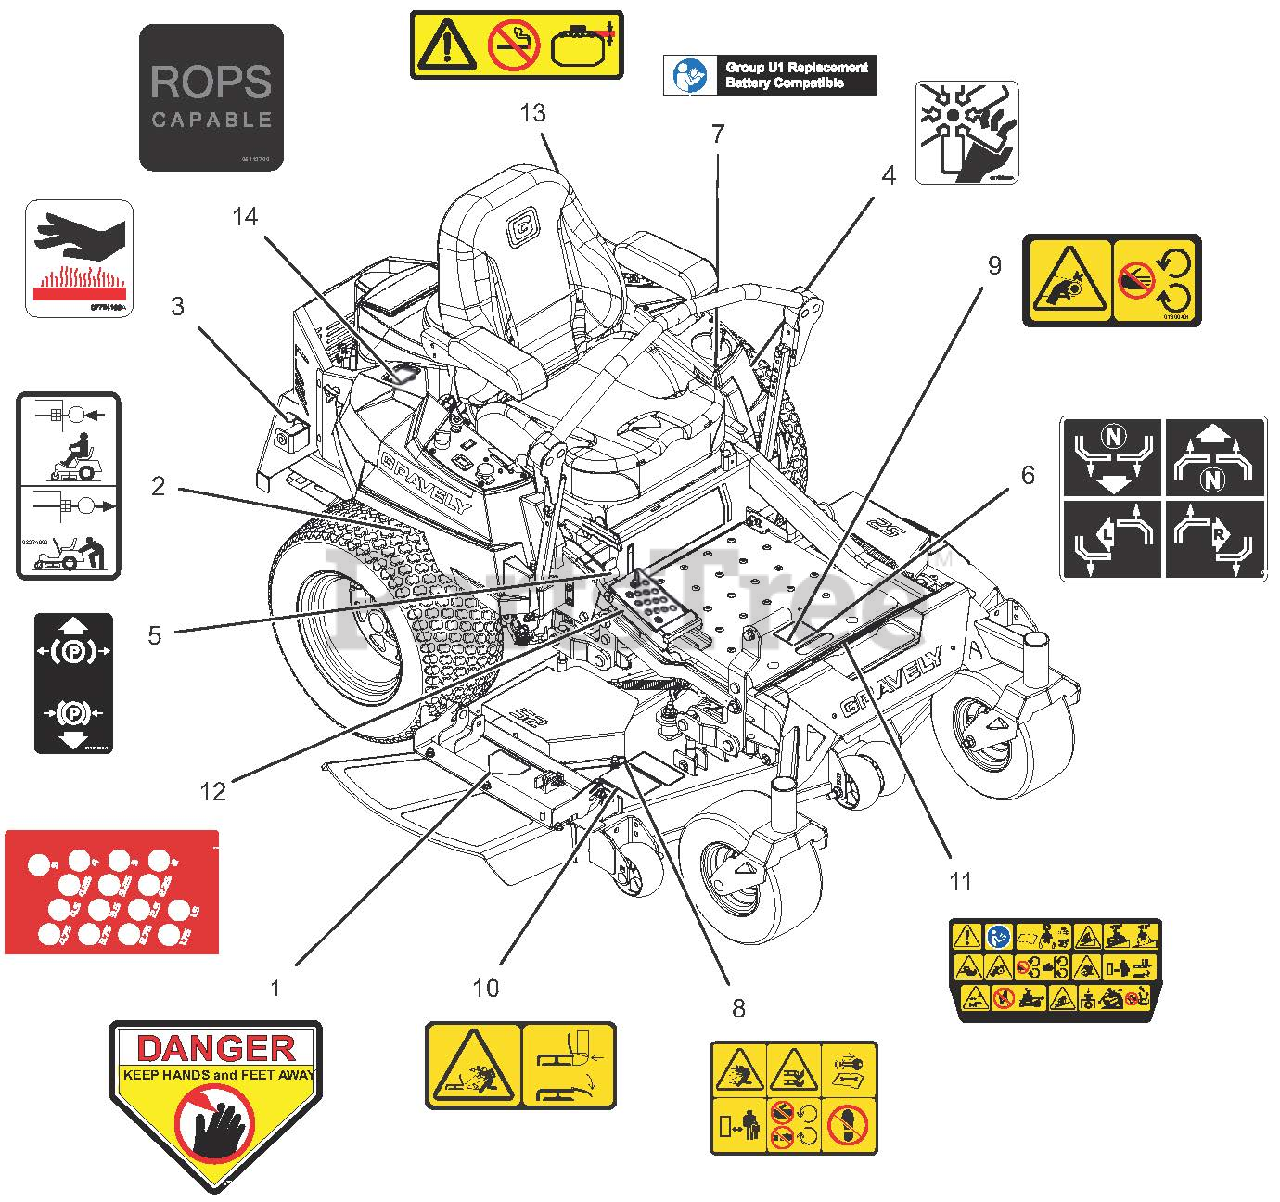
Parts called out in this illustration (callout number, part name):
1	DECAL, DANGER
2	DECAL, TRANSMISSION DISCONNECT
3	DECAL, HOT SURFACE
4	DECAL, DANGER FAN
5	DECAL, PARKING BRAKE LEVER
6	DECAL, INSTRUCTIONAL-STEERING
7	DECAL, U1 BATTERY REPLACEMENT
8	DECAL, SAFETY - MOWER DECK
9	DECAL, SAFETY - GUARDING
10	DECAL, SAFETY - DECK GUARDING
11	DECAL, MAIN SAFETY
12	DECAL - HOC
13	DECAL, FUEL WARNING
14	DECAL, ROPS LOCATION
